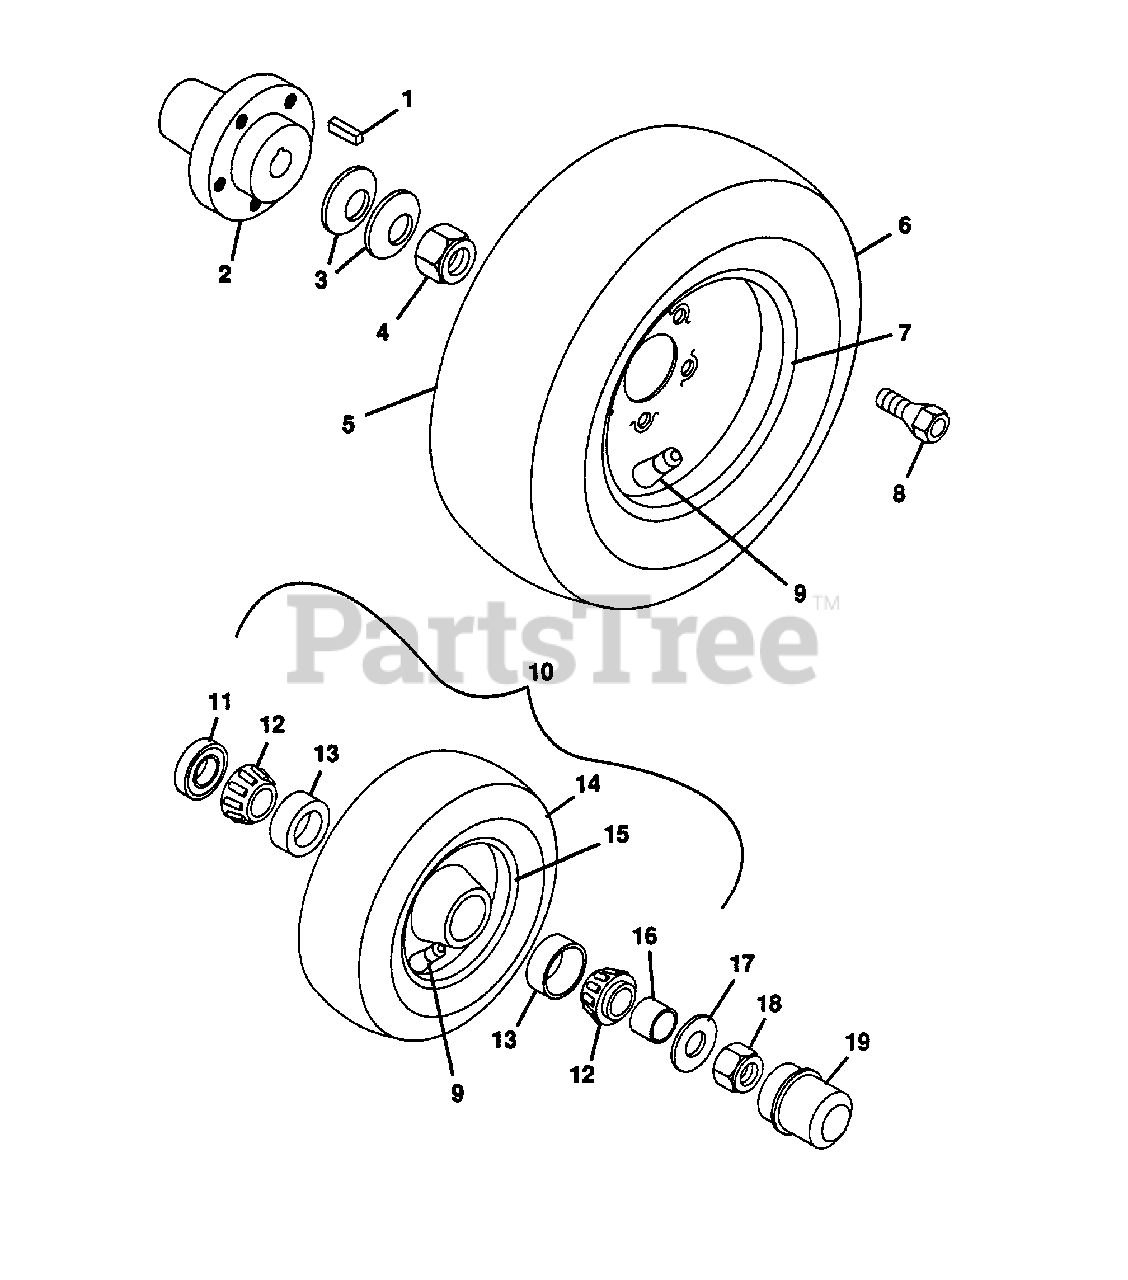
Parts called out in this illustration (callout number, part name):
1	Key, Square .312x2.25
2	Hub, Wheel
3	Spring, Belleville
4	Nut, Lock 1-14
5	Assembly, Wheel 23x10.50-12
6	Tire, Rear 23x10.50-12
7	Weldment, Rim Rear
8	Bolt, Hub 7/16-20x.75 Special
9	Assembly, Valve Stem
10	Tire, Assembly
11	Seal, Oil
12	Bearing, Cone LM 11949
13	Bearing, Cup LM 11910
14	Tire, Front 16x7.50-8
15	Weldment, Rim Front
16	Spacer
17	Washer, Flat .656x1.312x.095
18	Nut, Lock 5/8-11
19	Cap, Dust
